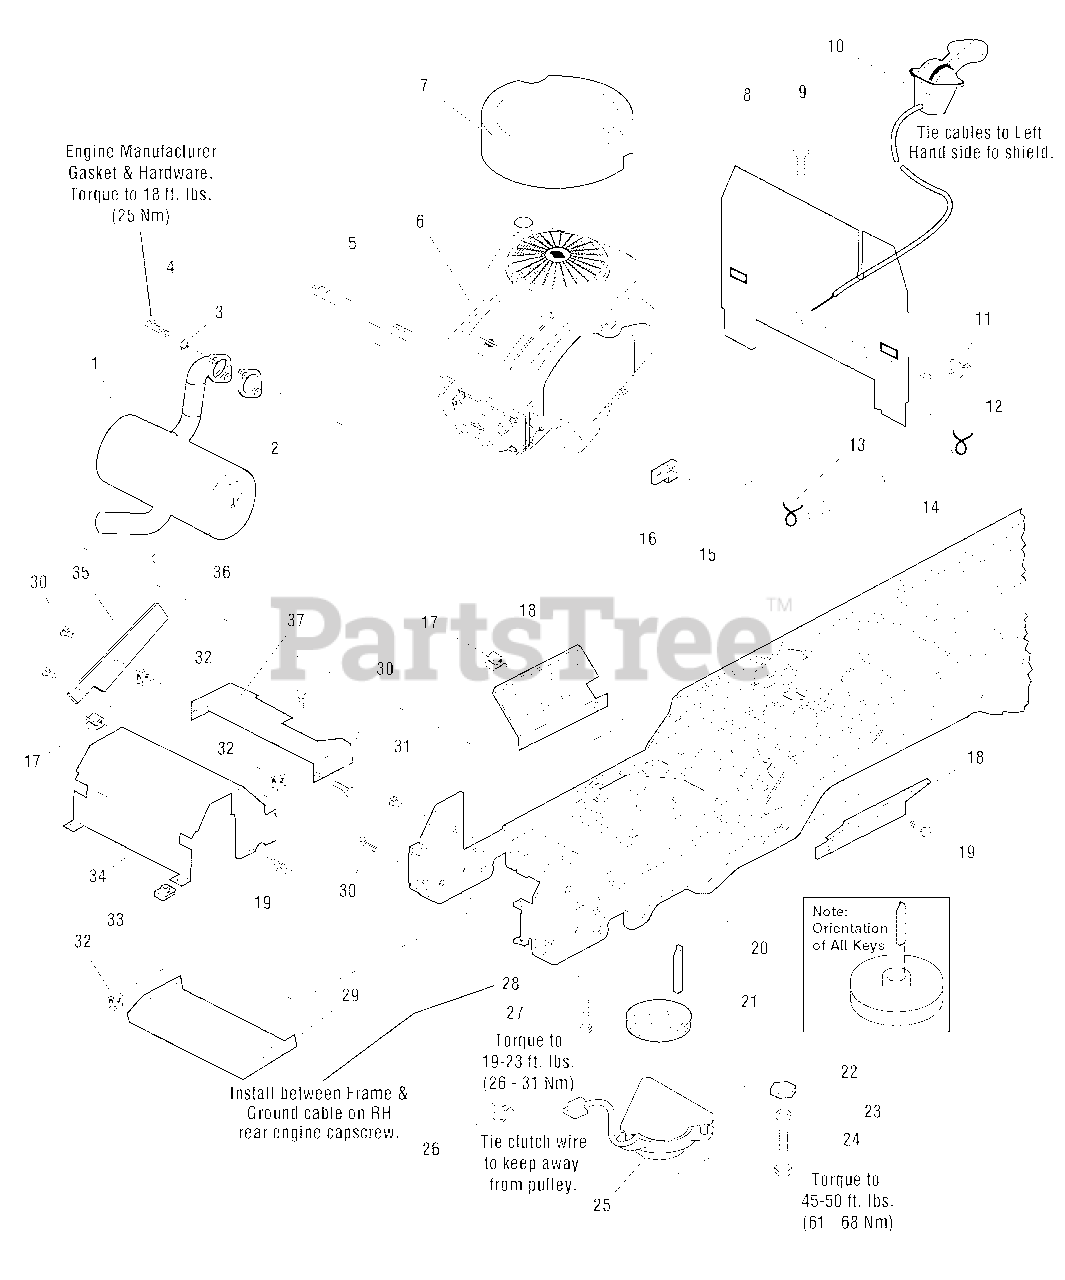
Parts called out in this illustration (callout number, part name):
1	MUFFLER
2	* GASKET
3	LOCKWASHER, 5/16
4	CAPSCREW, Socket Head, 5/16-18 x 7/8, G8
5	HOSE, Oil Drain
7	SEAL, Circle
8	BULKHEAD
9	CAPSCREW, Hex Head Taptite, 1/4-20 x 1/2
10	CONTROL, Throttle/Choke
11	TIE
12	EDGING, Rubber
13	CLAMP, Hose Type E
14	HOSE, 59" Long
15	SCREW, Trox Head Taptite, #8-32 x 1/2
16	PLATE, Limiter RPM
17	CLIP, Wire
18	SHIELD
19	SCREW, Hex Head Taptite, 1/4-20 x 3/8
20	KEY
21	PULLEY & HUB ASSEMBLY, 4-1/2 OD
22	WASHER, Hex
23	LOCKWASHER, 7/16
24	CAPSCREW, Hex Head, 7/16-20 x 2-3/4
25	CLUTCH, Electric, OGURA
26	TIE
27	CAPSCREW, Hex Head Taptite, 3/8-16 x 1-1/2
28	LOCKWASHER, External Tooth, 3/8
29	SHIELD, Muffler Bottom
30	CAPSCREW, Hex Head Flange Lock1/4-20 x 5/8
31	CAPSCREW, Hex Head Taptite, 5/16-18 x 1/2
32	NUT, Speed, 1/4-20
33	NUT, Speed, Lug Type, 5/16-18
34	DUCT, Muffler Top
35	GUARD, Manifold Pipe
36	CLIP, Wire
37	DUCT, Muffler Extension
